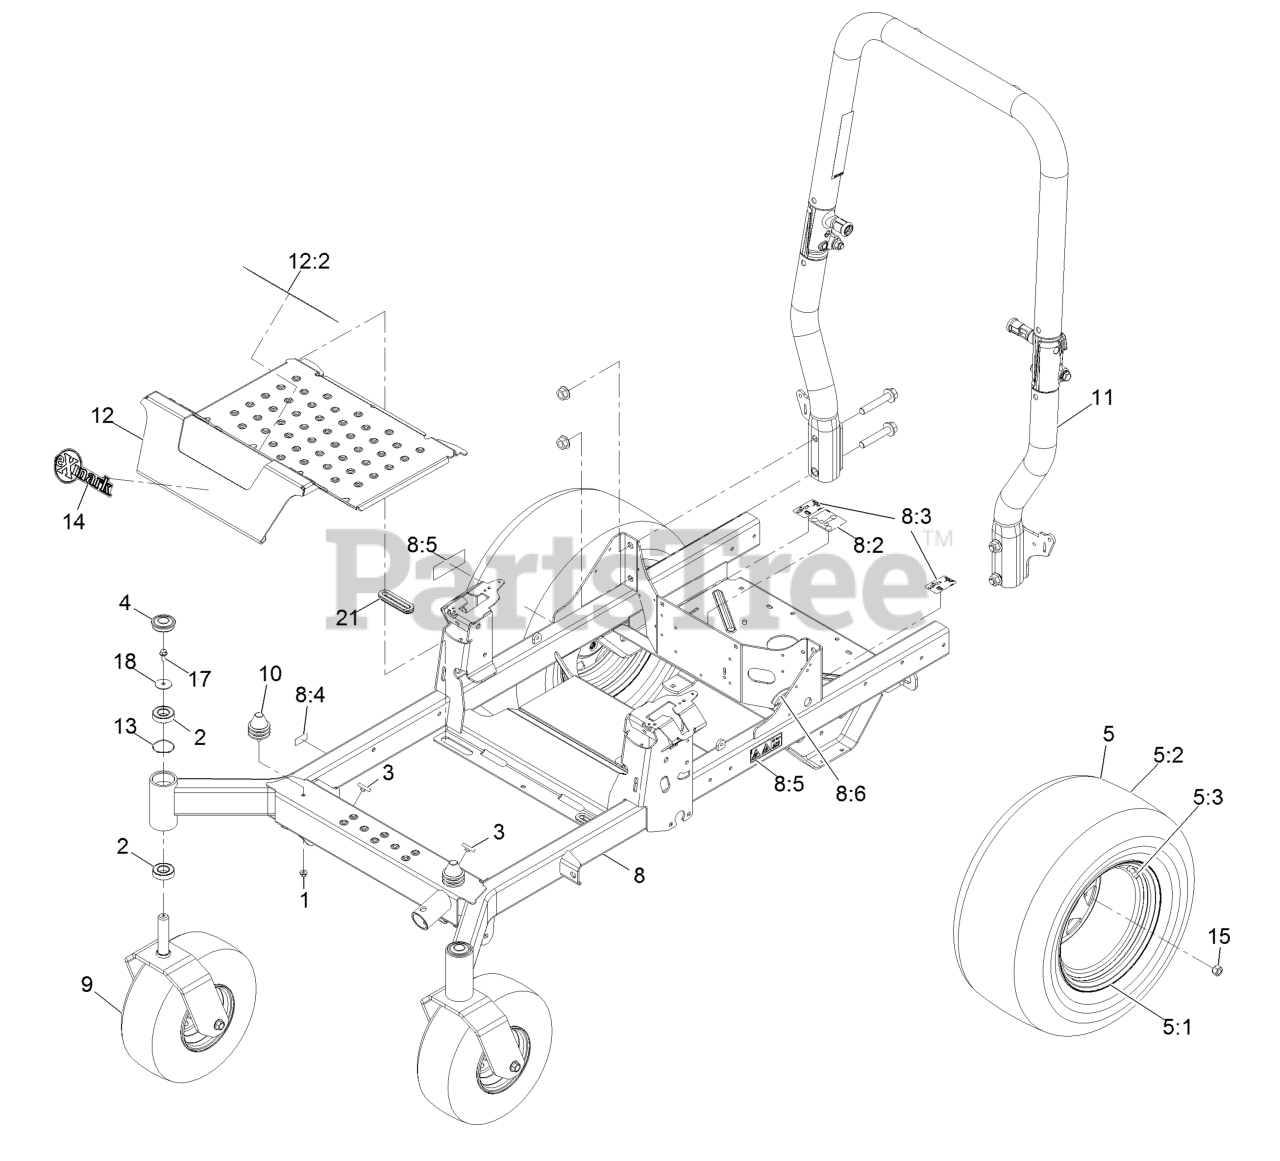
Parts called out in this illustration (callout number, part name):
1	NUT-HF, NI
2	BEARING-BALL
3	BUMPER-PUSH-IN, RUBBER
4	CAP-GREASE
5	WHEEL AND TIRE ASM
5:1	WHEEL RIM 12X8.5
5:2	TIRE
5:3	Stem-Valve
8	FRAME ASM
8:2	DECAL-ROUTING, BELT
8:3	DECAL-RELEASE, DRIVE
8:4	Decal-Patent
8:5	DECAL-WARNING
8:6	STRIP-SEAL
9	ASM-Front Caster W/Fork
10	ISOLATOR
11	ASM-ROPS TAPERED
12	PAN-FLOOR
12:2	DECAL-DANGER
14	DECAL-EXMARK LOGO
15	NUT-LUG
17	SCREW-HHF
18	WASHER-FLAT
21	GROMMET-RUBBER
